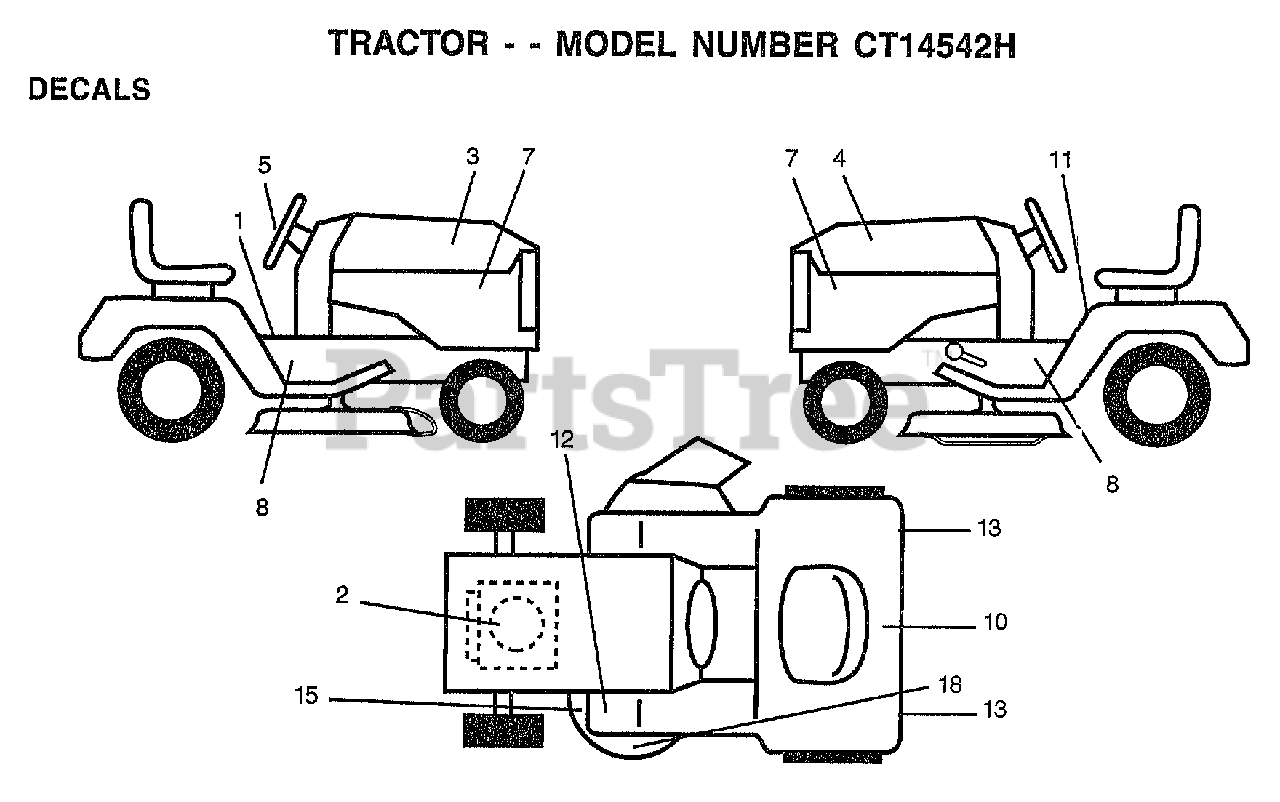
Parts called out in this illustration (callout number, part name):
1	"DECAL DASH,OPER."
2	DECAL.ENGINE
5	DECAL INST STG WH
7	DECAL SIDE PANEL
8	"DECAL CHASSIS 42"""
10	DECAL.BATRY.3-3908
11	"DECAL DANGER,FEND"
13	REFLECTOR-TAIL YT
15	"DECAL-SCHEM,BELT"
18	"DECAL,ENVIRO DECK"
